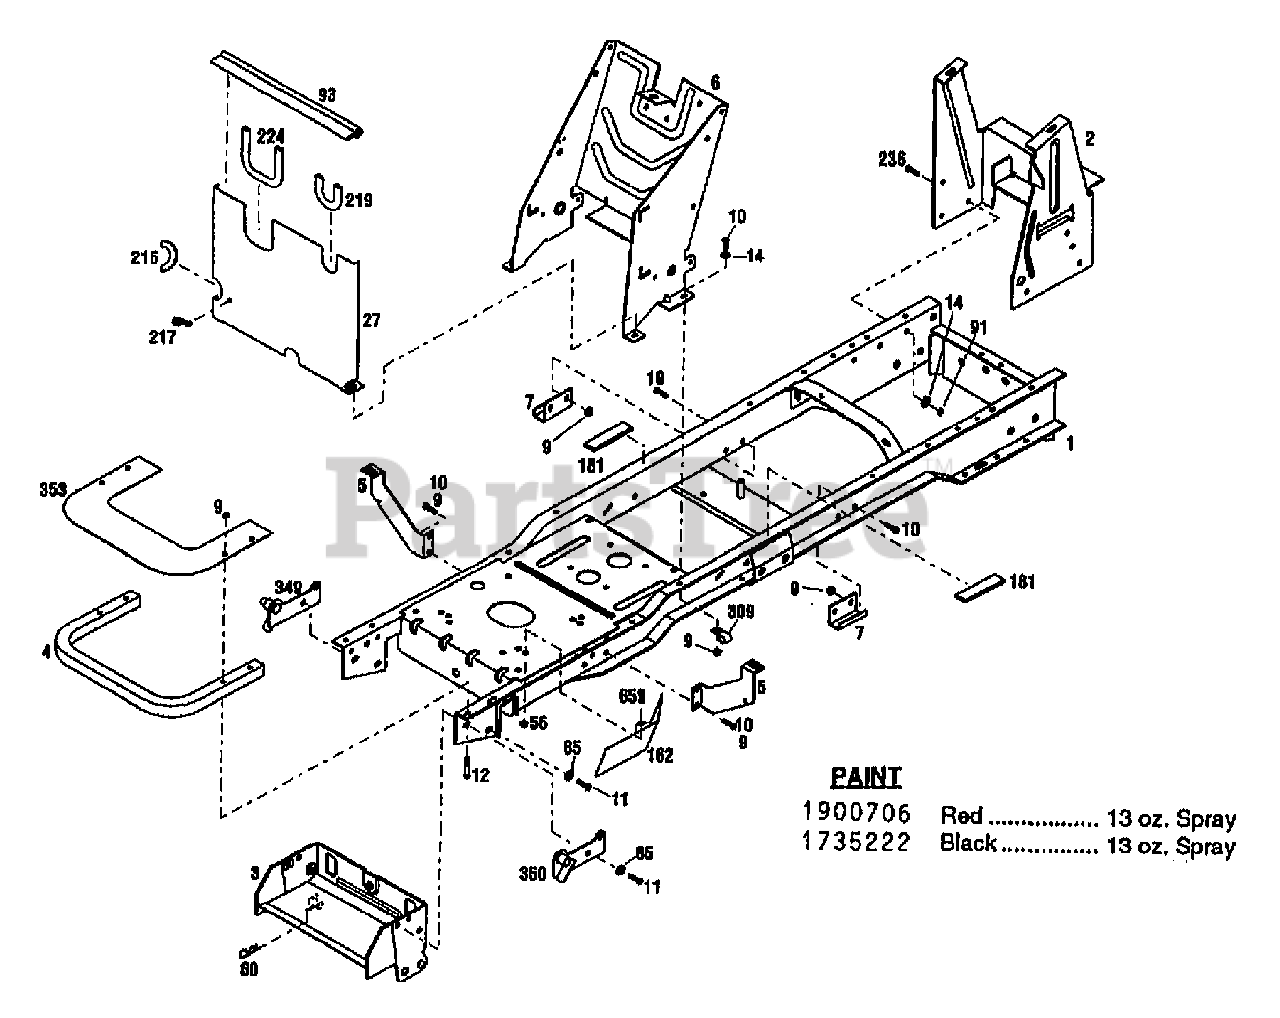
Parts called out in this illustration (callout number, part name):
2	SUPPORT-REAR TANK
3	ASSM-BRKT ATTACHMENT
4	BUMPER-FRONT
5	SUPPORT-FENDER
6	SUPPORT-CONSOLE
7	STOP-MOWER DECK
9	NUT-HFLK 5/16-18 ZP
10	SCR-HHC 5/16-18X.75 GR 5 ZP
11	SCR-HH 3/8-16X1.0 G5 ZP
12	SCR-HH 5/16-18X1.5 G5 ZP
14	WASHER-FLAT 5/16 SAE
27	SHIELD-HEAT
56	NUT-HF/LK 1/4-20 ZP
60	PIN-HITCH .125X2.56 ZP
65	SCR-HH 1/4-20X.625
91	NUT-TOP/LK 5/16-18 ZP
162	SHIELD-HEAT UPPER
217	HANGER-CABLE
224	TRIM-HEAT SHIELD
236	SCR-HFLK 5/16-18X.75 ZP
309	CLIP-J
349	PLATE-PIVOT RH
350	PLATE-PIVOT LH
353	SHIELD-HEAT
